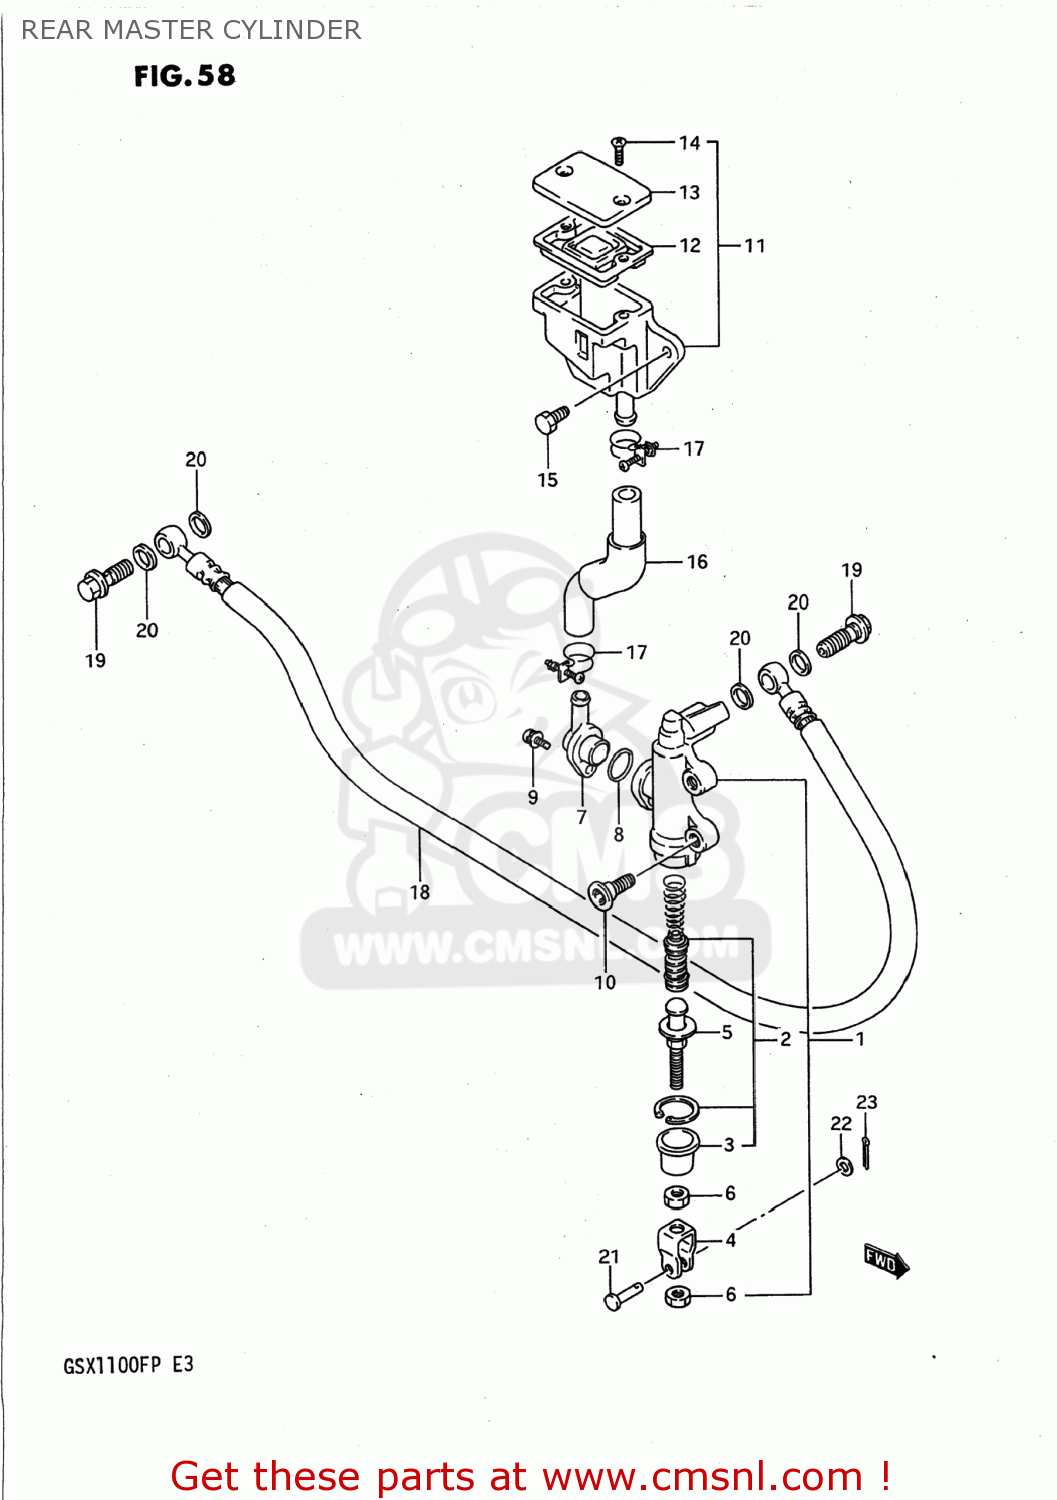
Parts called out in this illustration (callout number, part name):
1	CYLINDER ASSY,RR MASTER
2	PISTON/CUP SET
3	BOOT
4	YOKE
5	ROD,PUSH
6	NUT
7	CONNECTOR
8	O RING
9	SCREW
10	BOLT(8X15)
11	TANK ASSEMBLY,RESERVOIR
12	DIAPHRAGM
13	CAP
14	SCREW
15	BOLT
16	HOSE,RESERVOIR TANK
17	CLAMP
18	HOSE,REAR BRAKE
19	BOLT UNION
20	WASHER(10X15X1.5)
21	PIN
22	WASHER
23	PIN
